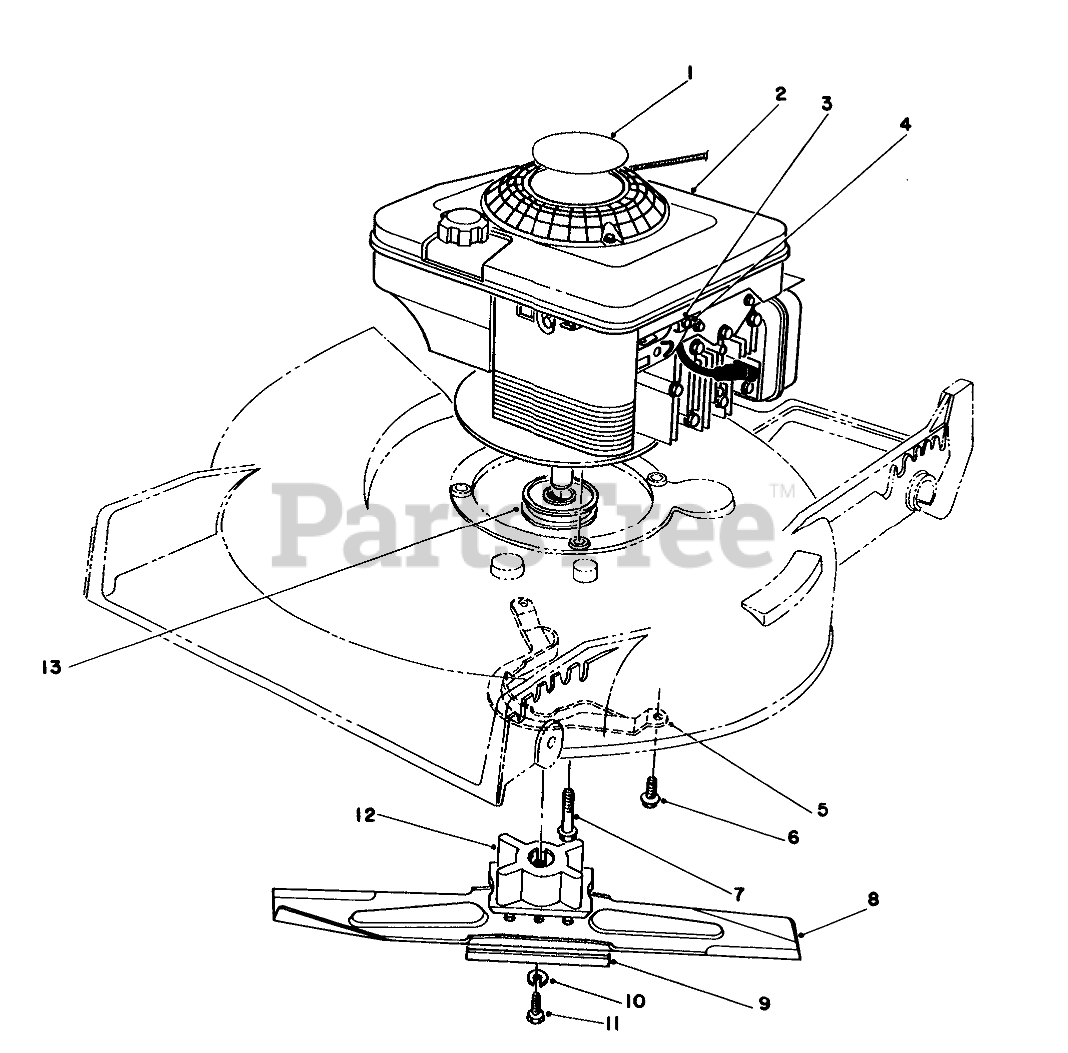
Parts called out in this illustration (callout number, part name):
1	DECAL - RECOIL
3	CLAMP-CASING
4	Screw
5	Guide-Belt
6	SCREW-HWHTF
7	SCREW-HWH
8	Blade-21" (Incl. Ref. #9)
9	Stiffener
10	WASHER-LOCK
11	SCREW-BLADE
12	BLADE RETAINER
13	PULLEY-DRIVE, ZONE START
